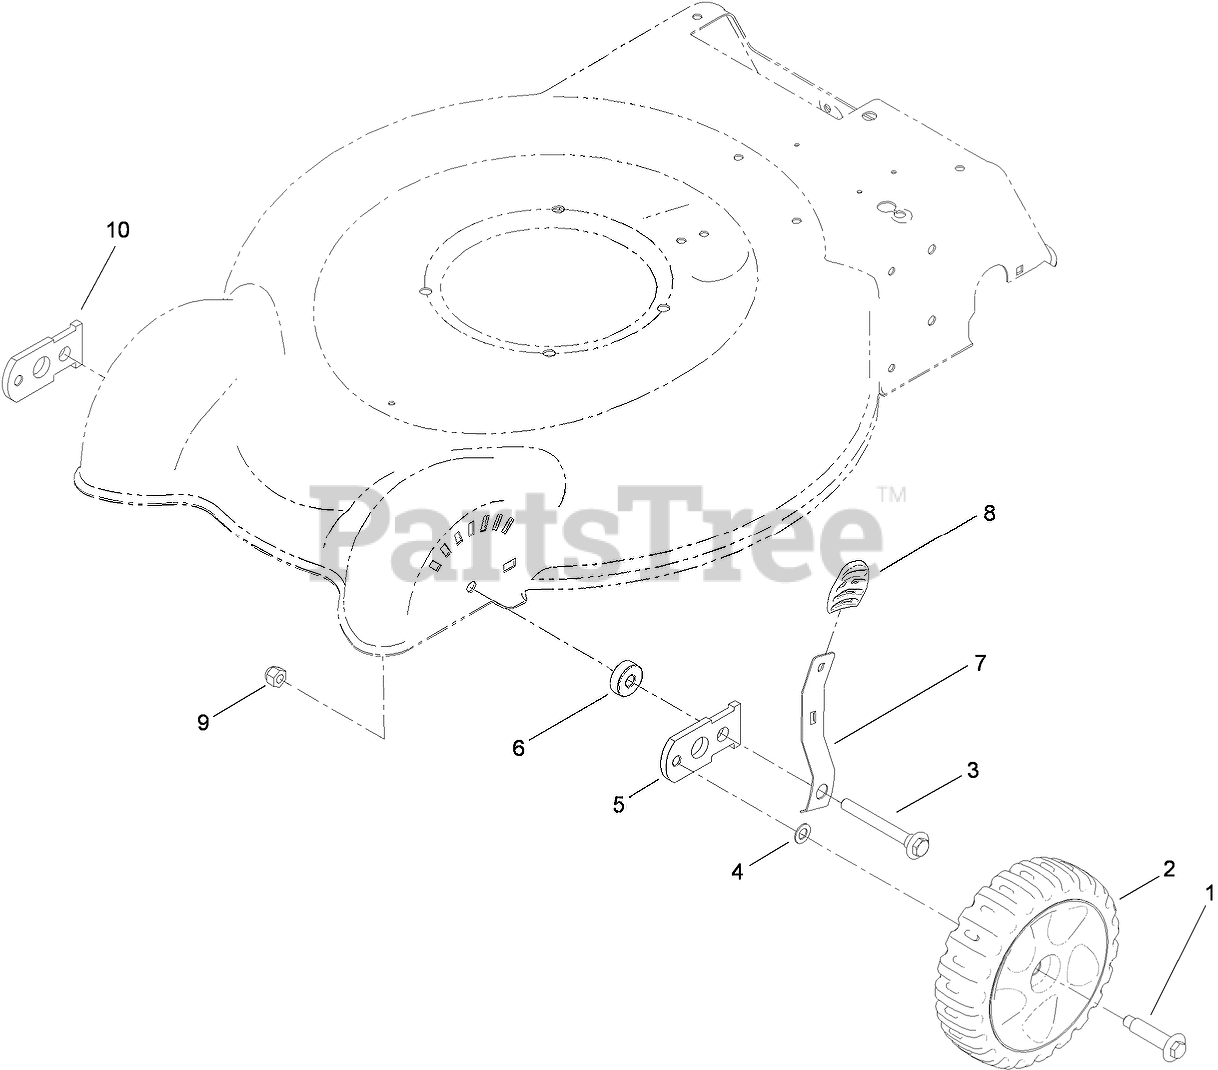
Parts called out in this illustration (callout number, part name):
1	BOLT-SHOULDER
2	7 INCH WHEEL AND TIRE ASM
3	BOLT-SHOULDER
4	WASHER
5	ARM-PIVOT, RH
6	SPACER-ARM, PIVOT
7	ARM-SPRING, FRONT
8	Knob-Lever, HOC
9	NUT-LOCK, NI
10	ARM-PIVOT, LH
